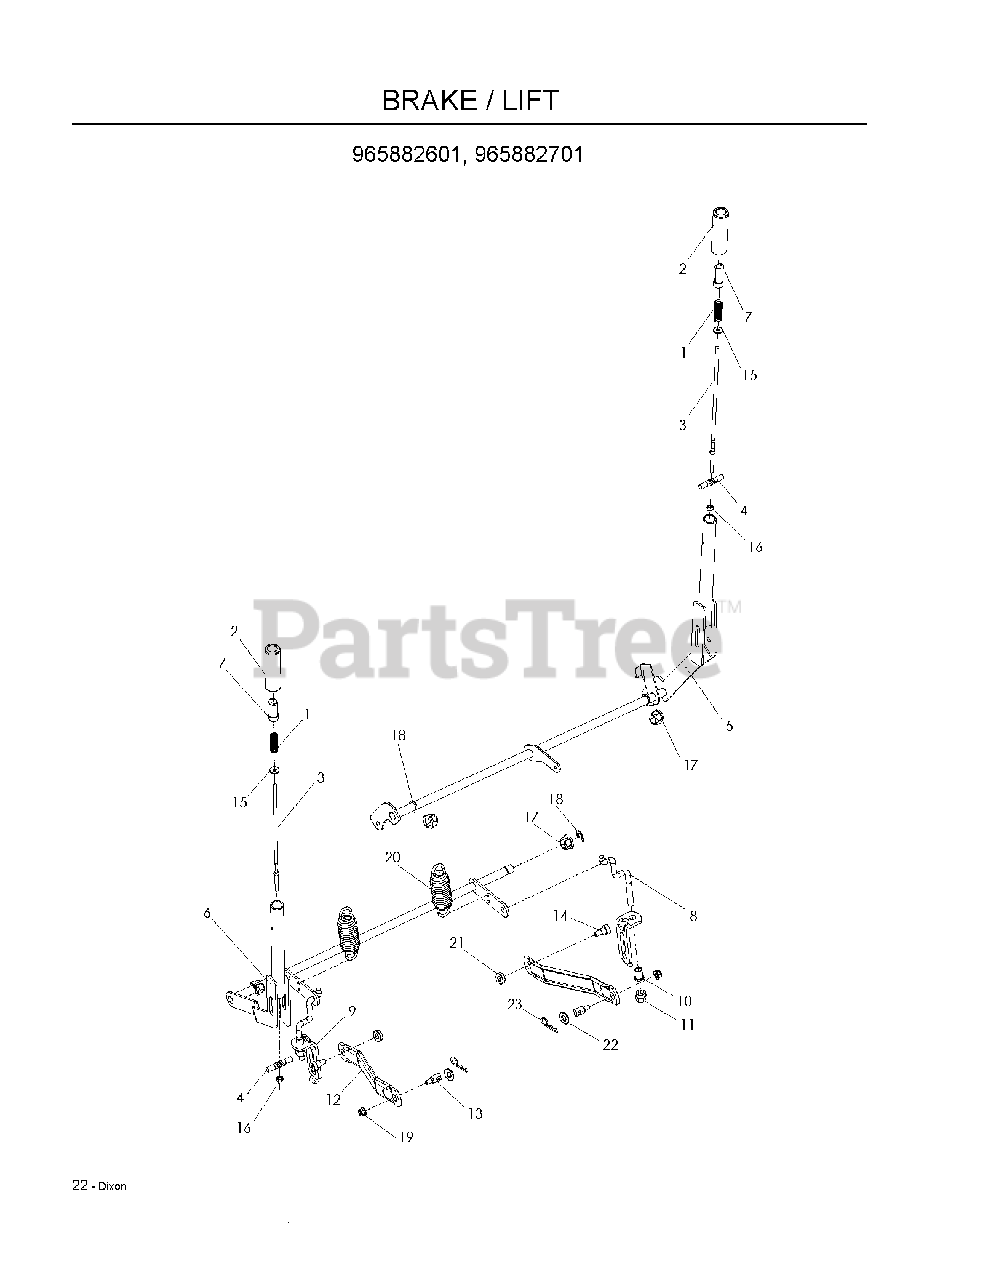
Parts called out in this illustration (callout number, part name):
1	SPRING, COMPRESSION
2	GRIP, HANDLE, BLACK
3	ROD, HANDLE RELEASE
4	ROD, LATCH RELEASE
5	SHAFT.ASSY.BRAKE.WLDMT.BLACK
6	SHAFT, LIFT, BLK
7	BUTTON, PUSH, BLACK (2 2)
8	LINK, REAR SUSPENSION
9	BRACKET CONNECT LINK LIFT
10	BUSHING ALIGNMENT LINK LIFT
11	NUT, LIFT LINK 7/16-20
12	ARM.SUSPENSION.MOWER
13	STUD.FASTNER.W/ANTI-ROTATE
14	SB 3/8-16 X 3/8 SKT HD ZD
15	WASHER 1/4 FLAT
16	NUT 1/4-20 NYLOC
17	PLASTIC NUT
18	E-RING 5/8
19	5/16-18 NYLOC FLANGE NUT
22	WASHER 5/8 FLAT
23	HAIRPIN #4
